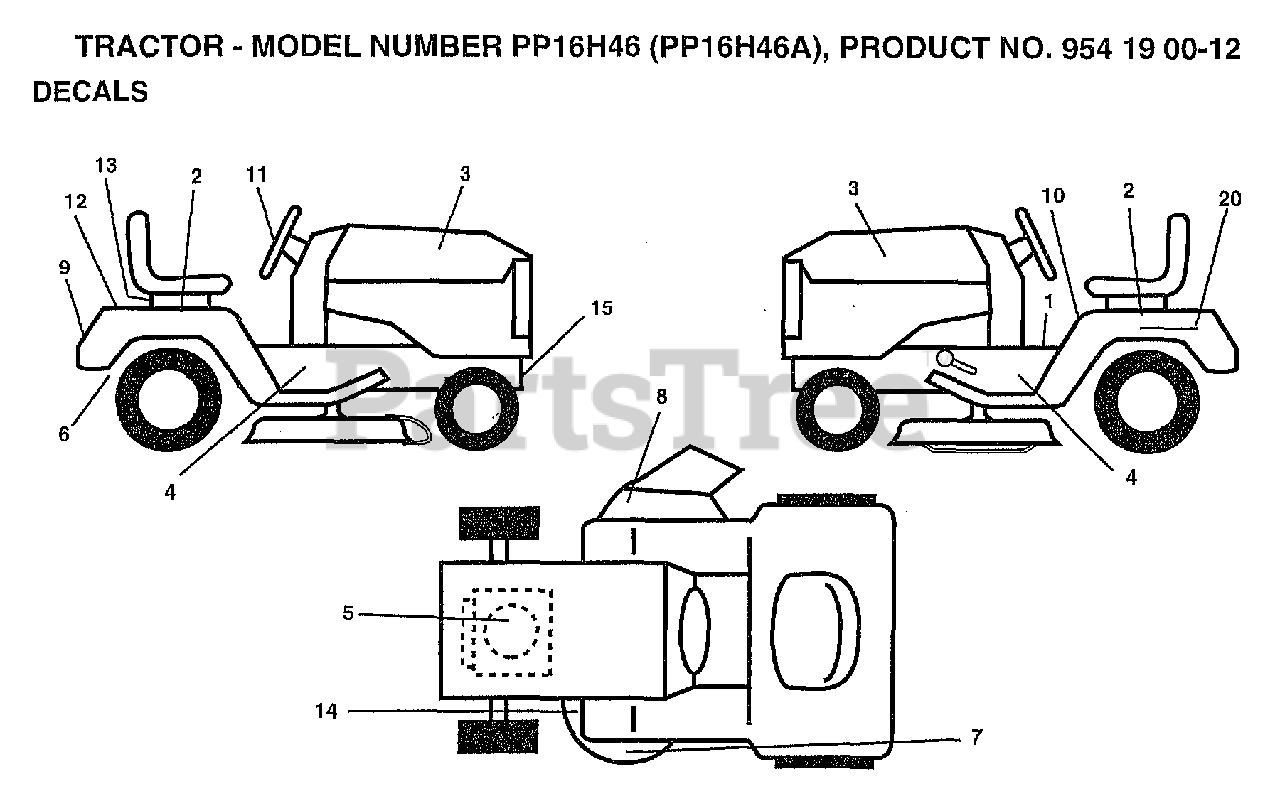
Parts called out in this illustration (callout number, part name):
1	"DECAL FENDER,OPER"
2	DECAL FENDER AUTO
3	DECAL HOOD PREDAT
4	"DECAL CHASSIS 46"""
5	DECAL, ENGINE B&S
6	DECAL DRAWBAR LH
7	"DECAL,ENVIRO DECK"
8	"DECAL, WARNING"
9	DECAL FENDER DOME
10	DECAL.CAUT.ENG/FR
11	DECAL INS STRG WH
12	DECAL FENDER PRED
13	RETAINER-SPRING
14	"DECAL.V.BELT.44"""
15	DECAL CHASSIS PRE
20	DECAL.BATRY.3-3908
